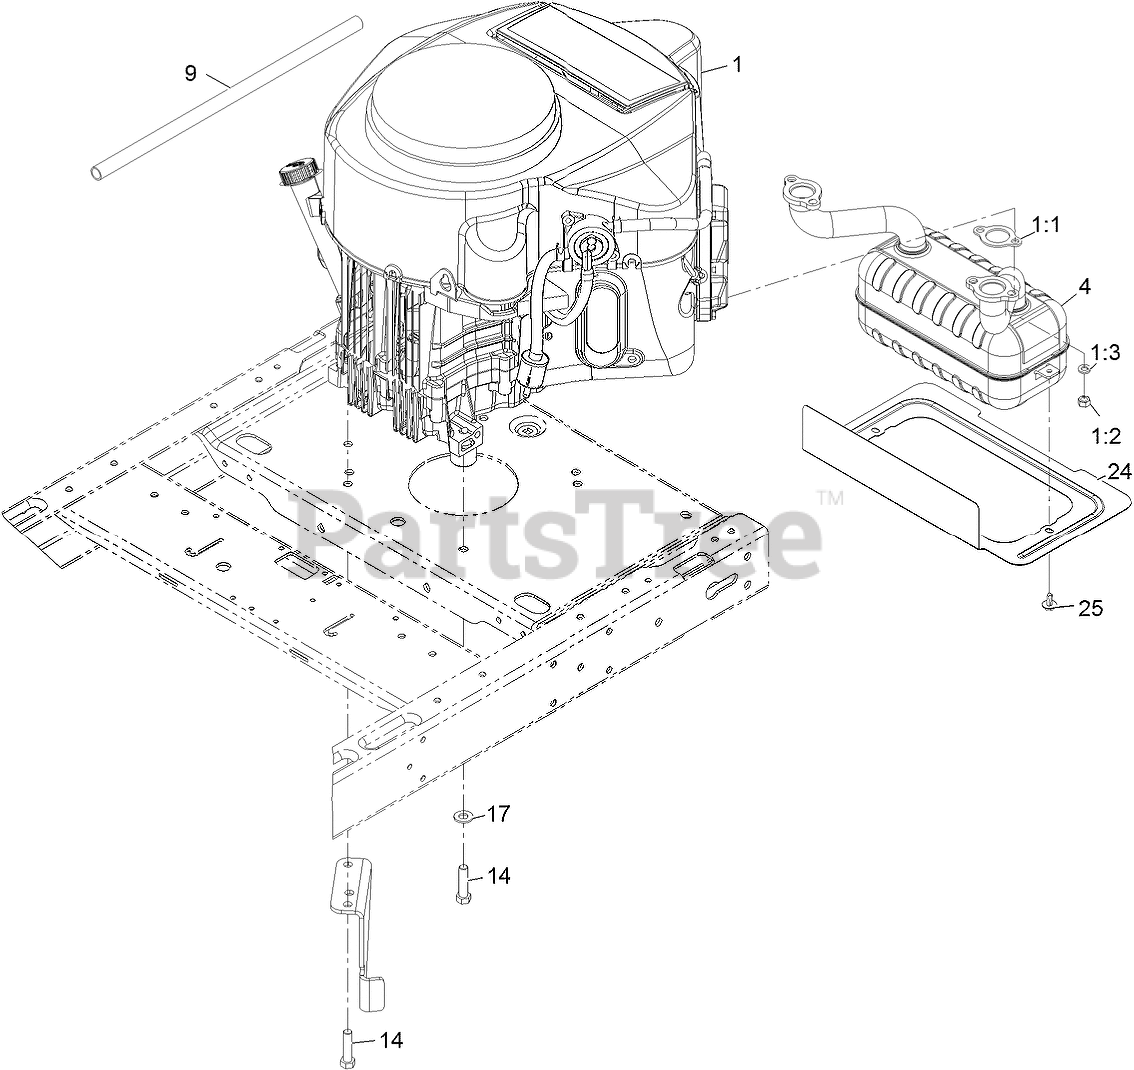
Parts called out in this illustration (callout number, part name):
1:1	GASKET-EXHAUST
1:3	WASHER-LOCK
4	MUFFLER-KAWASAKI
9	Hose-Oil Drain
14	BOLT-HH
17	WASHER-FLAT
24	SHIELD-HEAT
25	SCREW-HHFTF
